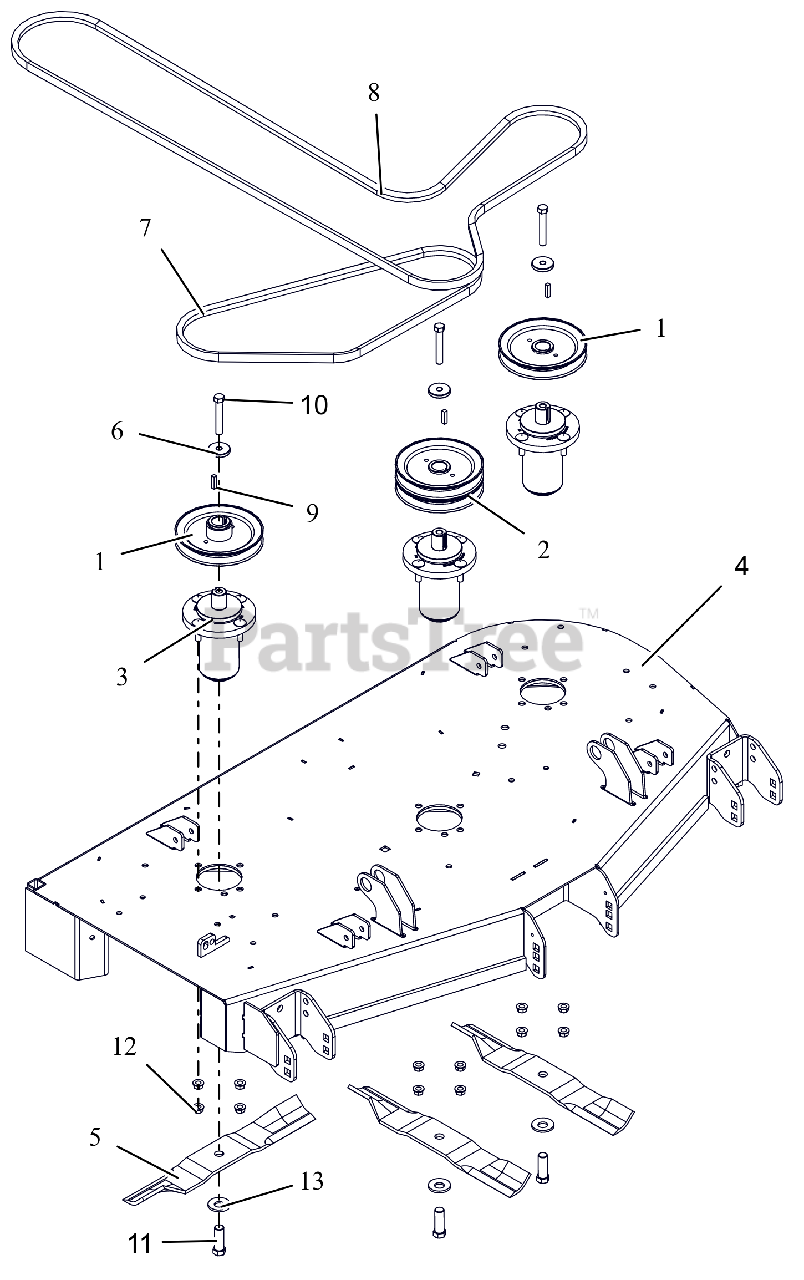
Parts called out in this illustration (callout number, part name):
1	PULLEY, SINGLE-1"ID X 6" OD
2	PULLEY, DOUBLE
3	ASM, MAINT FREE ALUM SPINDLE
4	KIT,DECK-48" W/DECALS-GRAVELY
5	BLADE, 16.19" MOWER (HI-LIFT)
6	RETAINER, SHEAVE
7	V-BELT, B-COGGED
8	V-BELT, HB SECTION
9	KEY, SQ .25X.25X1.00 RC 40-50
10	BLT, HEX 0.4375-20X2.75 G8 ZCC NT
11	BLT, HEX .62-18X1.75 G8 ZCC
12	NUT-LK-CTR-FLG .375-16 GF ZCC
13	WSHR-BLVL .669X1.535X.138
